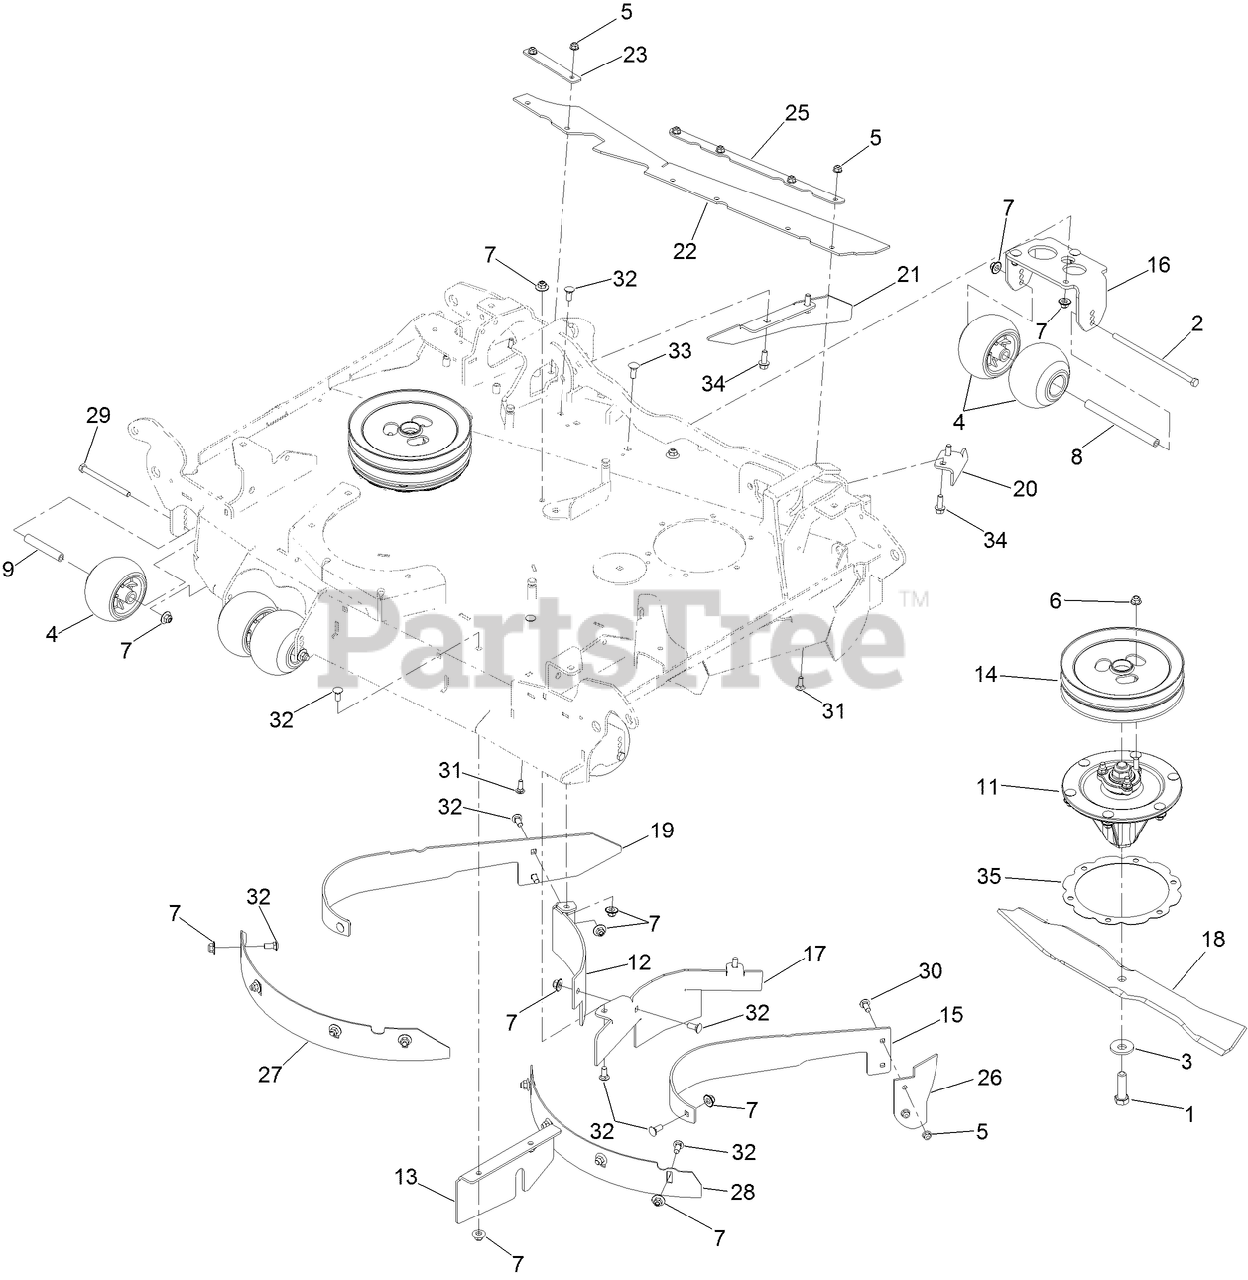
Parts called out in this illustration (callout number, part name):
1	SCREW-BLADE
2	SCREW-HH
3	WASHER-BLADE BOLT, HEAVY
4	ROLLER-SCALP, ANTI
5	NUT-HF, NI
6	NUT-HF, NI
7	NUT-FLANGE, NI
8	SPACER-WHEEL
9	SPACER-WHEEL SHORT
11	SPINDLE ASM
12	BAFFLE-CENTER, REAR (RH)
13	PLATE-BLOCK, FRONT
14	SHEAVE-DOUBLE
15	BAFFLE-DOGLEG, CENTER (LH)
16	BRACKET-ANTISCALP, REAR
17	BAFFLE-CENTER
18	BLADE-MULCH, 24.5IN
19	BAFFLE-DOGLEG, CENTER (RH)
20	BAFFLE-BREAKER
21	PLATE-FIN, DISCHARGE
22	FLAP-DISCHARGE
23	SUPPORT-FLAP, LH
25	SUPPORT-FLAP, LH
26	GUARD-DISCHARGE
27	BAFFLE-DEPTH, LH
28	BAFFLE-DEPTH, RH
29	SCREW-HH
30	SCREW-CARR
31	SCREW-CARR
32	BOLT-CARR
33	SCREW-HH
34	SCREW-HHF
35	RING-SPACER, HOUSING
